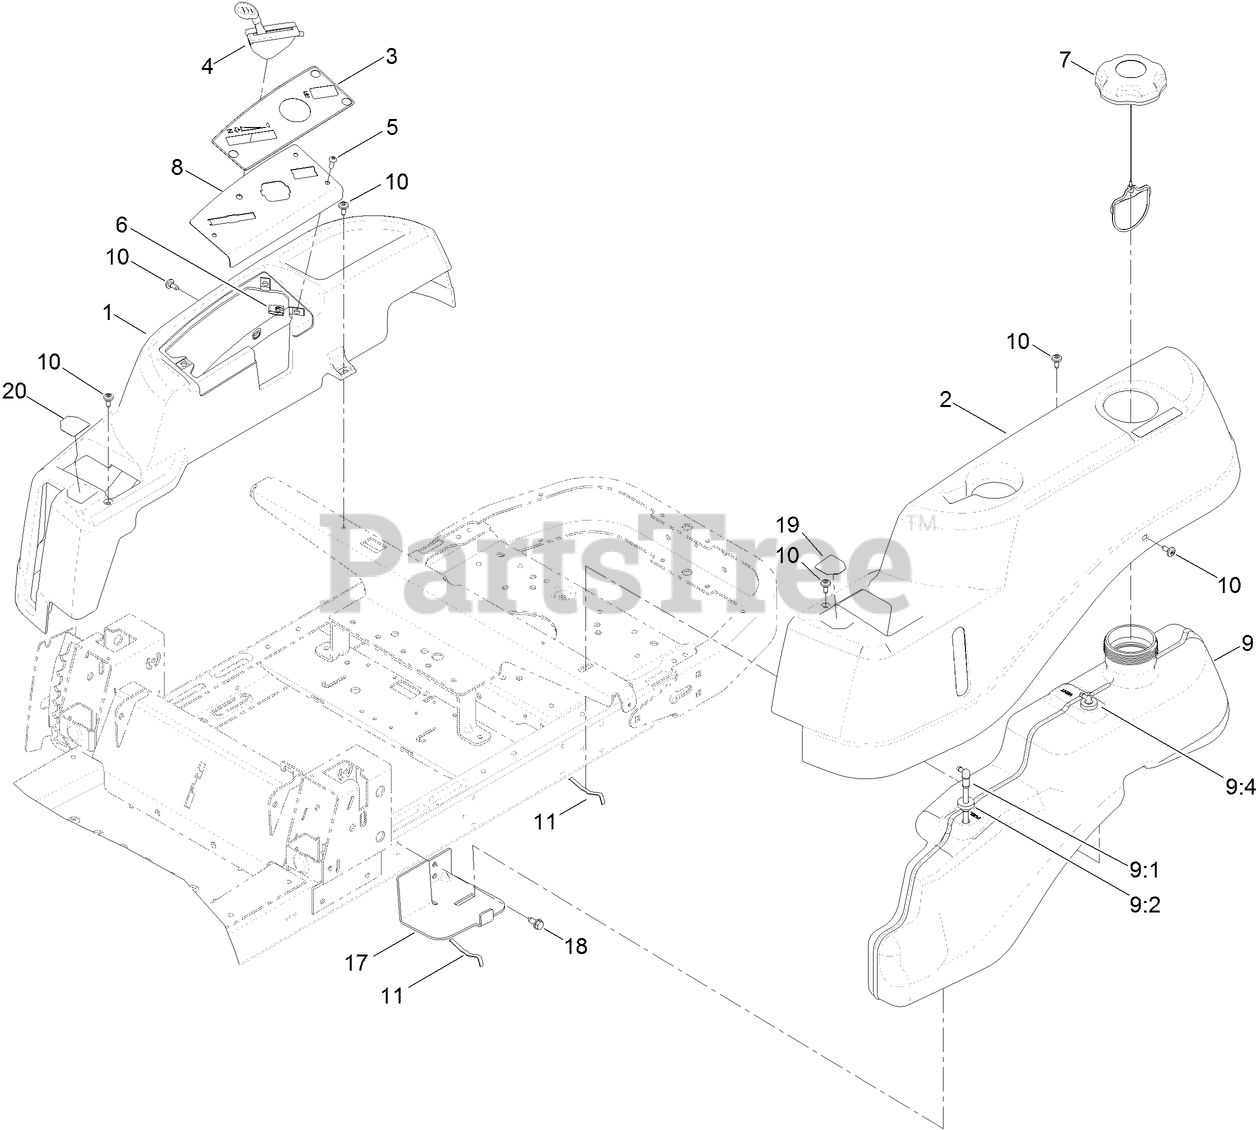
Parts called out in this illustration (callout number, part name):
1	POD-RH
3	DECAL-PANEL, CONTROL
4	CABLE-THROTTLE AND CHOKE
5	SCREW-PRH
8	PLATE-CONTROL
9	FUEL TANK ASM
9:1	CONNECTOR-ELBOW, 90 DEG
9:2	BUSHING
9:4	FITTING-PLASTIC
10	SCREW-SHOULDER
11	SPRING
17	SUPPORT-TANK, FRONT
18	SCREW-HWHTF
19	DECAL-LEVER, CONTROL (LH)
20	DECAL-LEVER, CONTROL (RH)
